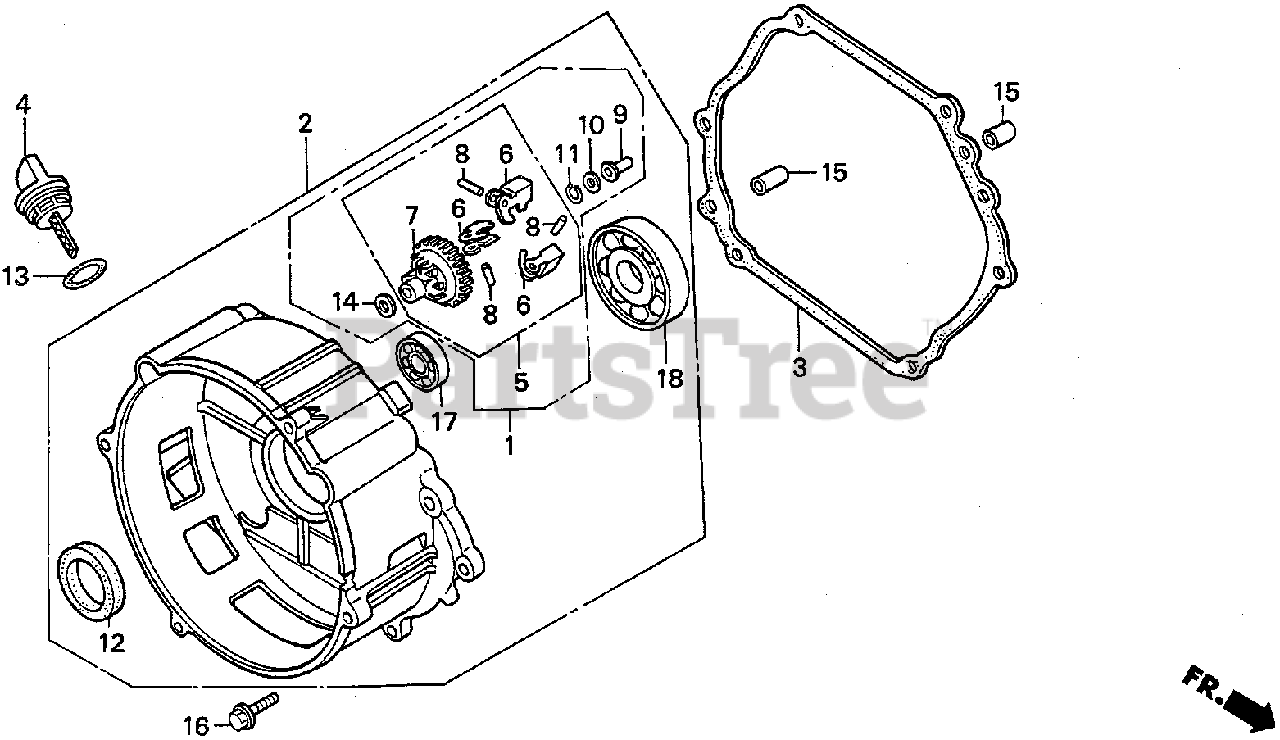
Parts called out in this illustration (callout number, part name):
1	GOVERNOR KIT Use from Engine SN 1421333.
1	GOVERNOR KIT Use up to Engine SN 1421332.
2	COVER ASSY., CRANKCASE (E-TYPE)
2	COVER ASSY., CRANKCASE (E-TYPE) (NOT AVAILABLE)
2	COVER ASSY., CRANKCASE
3	GASKET, CASE COVER
4	CAP, OIL FILLER
5	GOVERNOR ASSY.
6	WEIGHT, GOVERNOR
7	HOLDER, GOVERNOR WEIGHT
8	PIN, GOVERNOR WEIGHT
9	SLIDER, GOVERNOR
10	WASHER (6X16)
11	CLIP, GOVERNOR HOLDER
12	OIL SEAL (35X52X8)
13	O-RING (26X2.7)
14	WASHER, PLAIN (6MM)
15	PIN, DOWEL (8X12)
15	PIN A, DOWEL (8X12)
16	BOLT, FLANGE (8X40)
17	BEARING, RADIAL BALL (6202)
18	BEARING, RADIAL BALL (6207)
